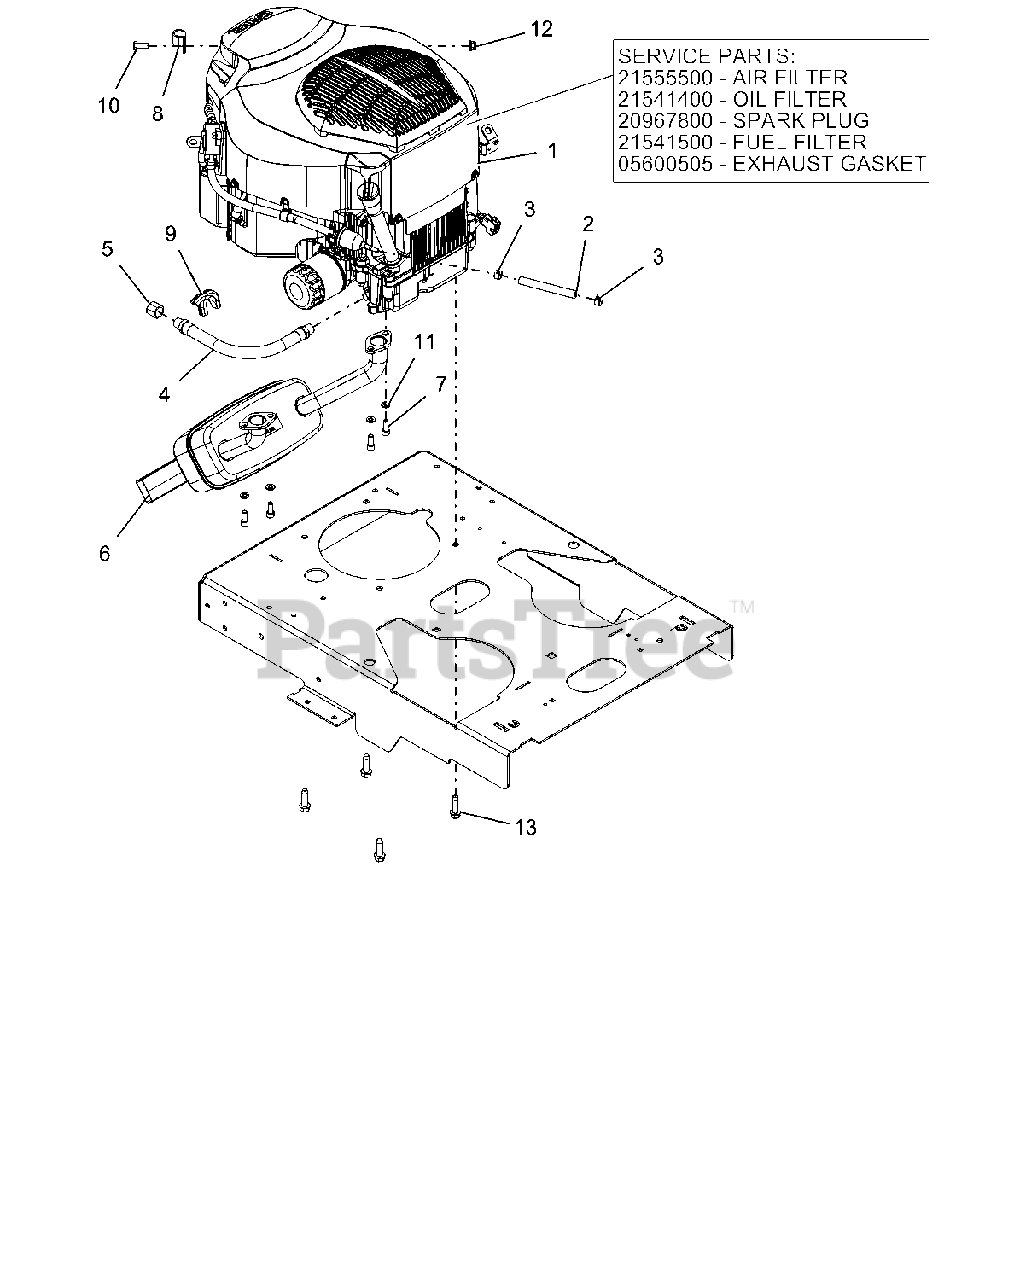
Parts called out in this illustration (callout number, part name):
1	ENGINE, KOHLER TWIN - 24HP-PRO W/SC
1	AIR FILTER
1	OIL FILTER
1	SPARK PLUG
1	FUEL FILTER
1	EXHAUST GASKET
2	.25 LOW-PERM GAS HOSE 21.50" LG - TANK TO ENGINE
3	CLAMP, FUEL LINE
4	HOSE, HYD .38-11-OK M6N0-M6N0
5	PIPE, CAP 3/8 NPT FEMALE
6	MUFFLER, KOHLER
7	SCR, CAP SOCKET HEAD
8	CLAMP, CUSHIONED STEEL .75
9	PROTECTOR, OIL DRAIN HOSE
10	BLT-HEX .31-18X.75 GR5 YWZC
11	WSHR-LK .31X.078 REG YWZC
12	NUT-LK-NYL-FLG .31-18 YWZC
13	SCR-TAP .38-16X1.25 HWH TR YZ
